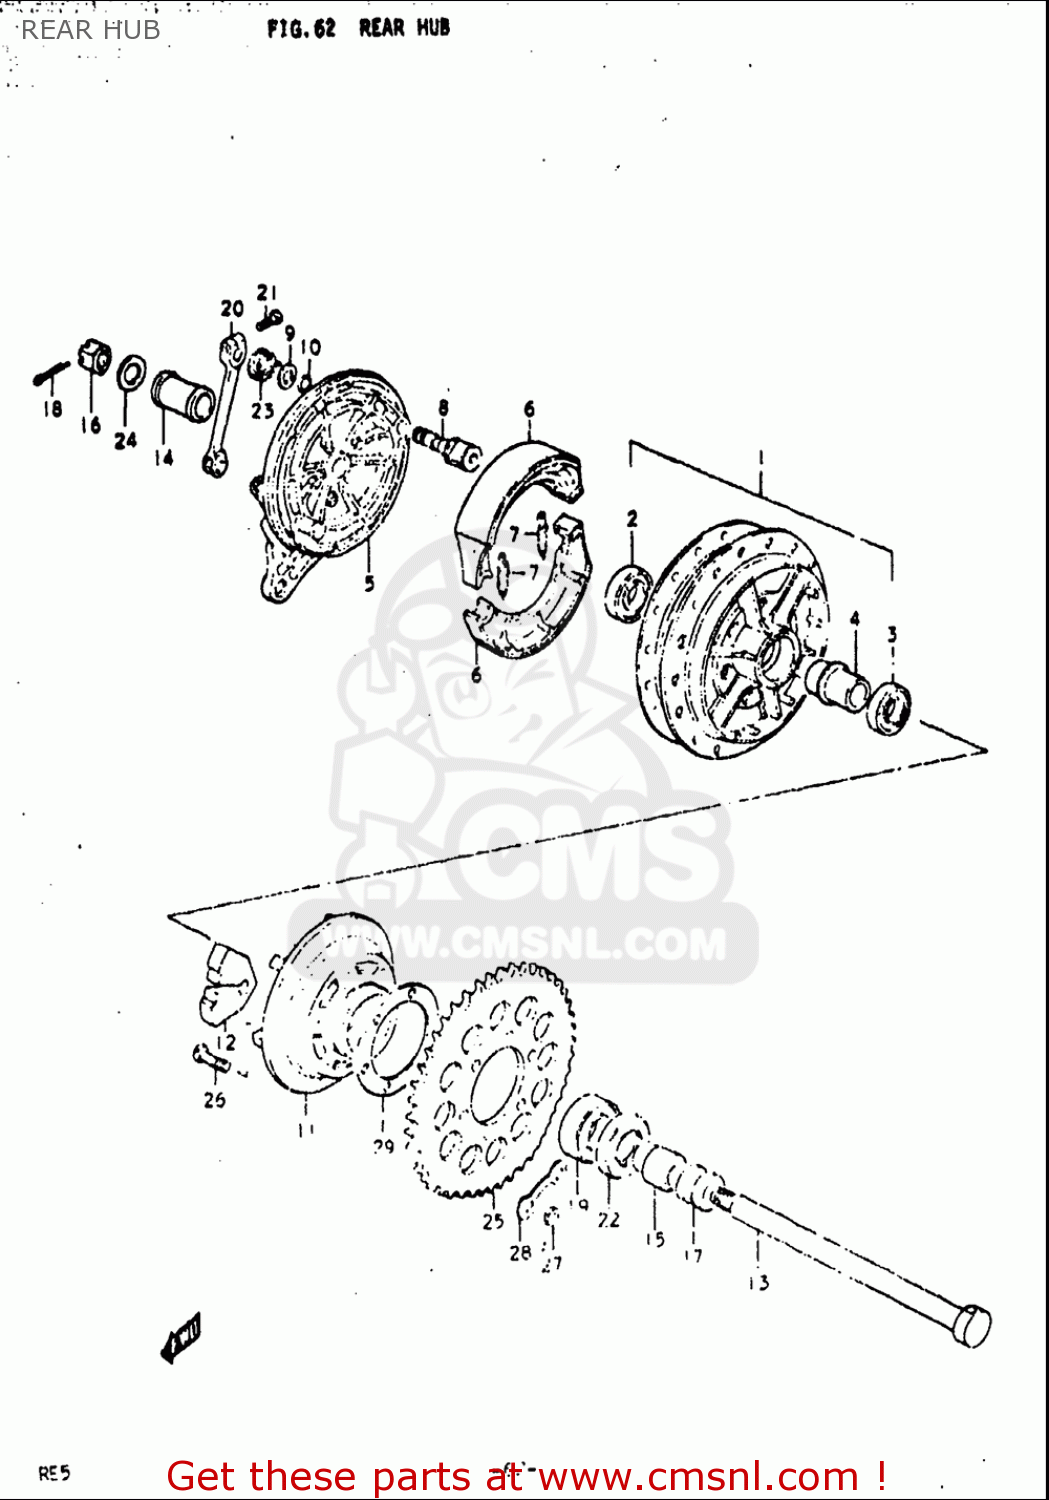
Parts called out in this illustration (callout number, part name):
2	BEARING
3	BEARING(20X47X14)
6	SHOE SET,BRAKE (NAS)
7	SPRING,BRAKE SHOE
8	CAM,RR BRAKE
9	WASHER(15.5X24X1.6)
10	O RING(D:2.4,ID:14.8)
11	DRUM,RR SPROCKET MOUNTING
12	ABSORBER,RR HUB SHOCK
15	SPACER,REAR HUB BEARING
16	NUT 18MM
17	SPACER(20X33X28.3)
18	PIN
19	BEARING(25X62X17)
21	BOLT
22	SEAL,OIL(33X62X7)
23	SPRING
24	WASHER(19X34X4)
26	BOLT(10X35.5)
28	WASHER
